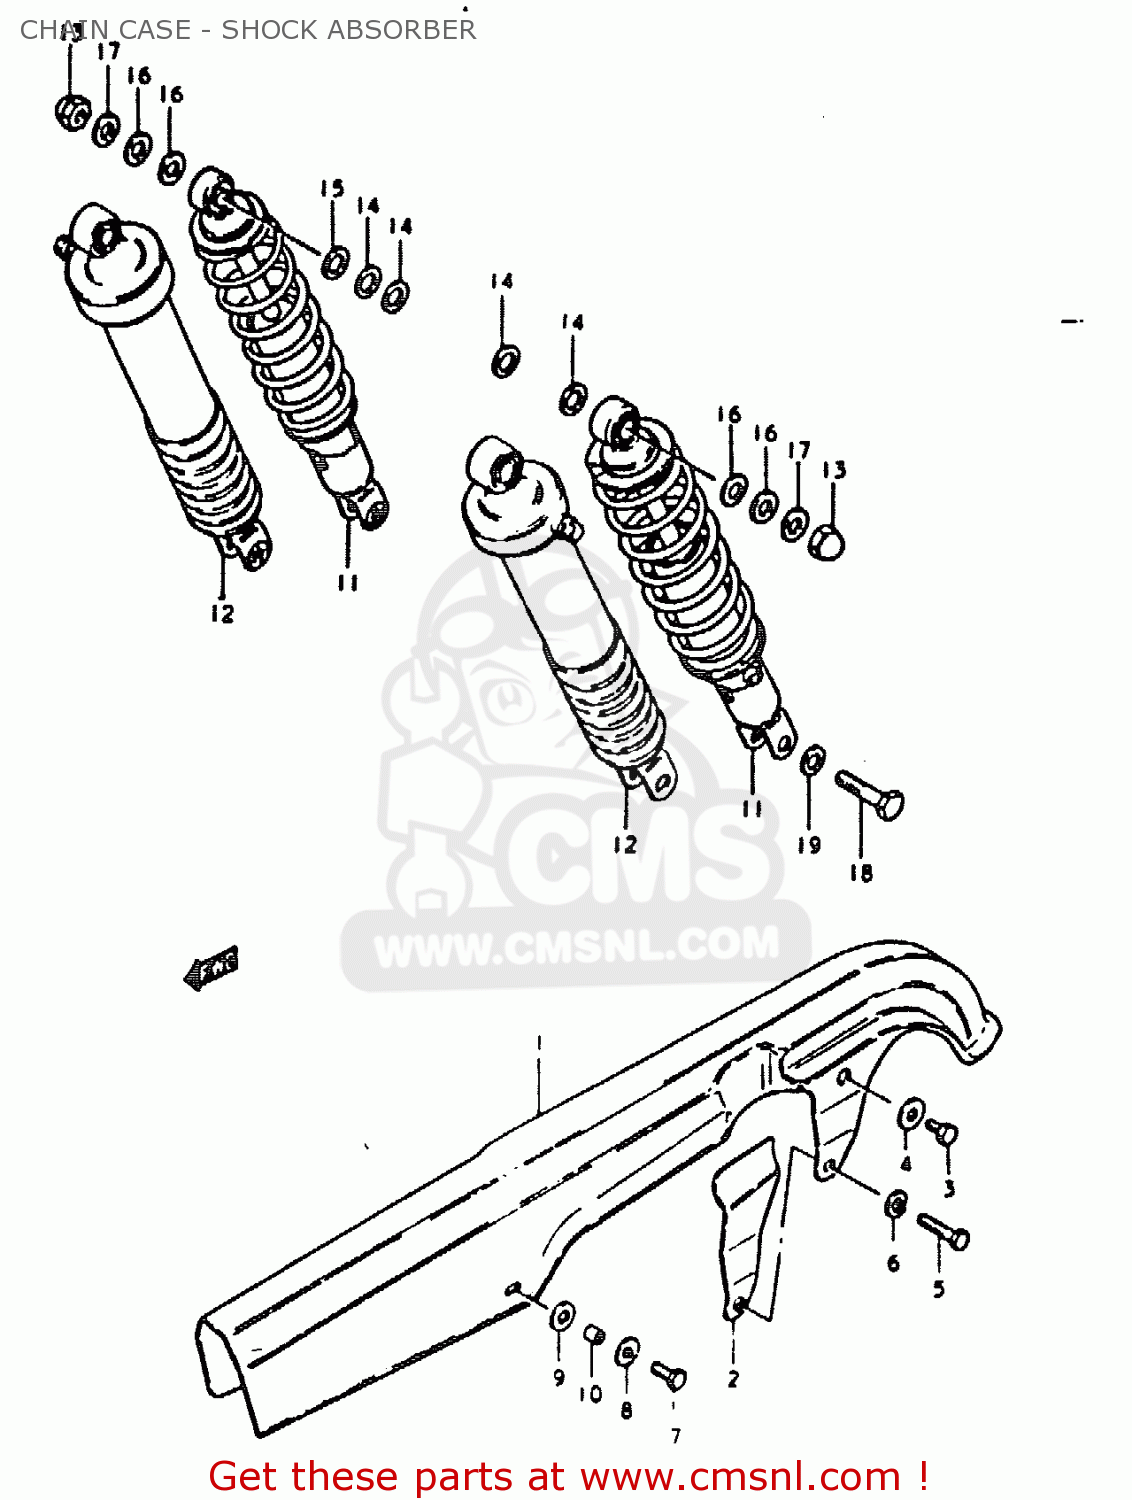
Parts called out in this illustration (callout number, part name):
1	CASE,CHAIN
2	REINFORCEMENT,CHAIN CASE
3	BOLT(6X8)
4	WASHER
5	BOLT
6	LOCK WASHER
7	BOLT
8	WASHER(6.5X18X1)
9	CUSHION
10	SPACER (6.1X8X5.2)
11	ABSORBER ASSEMBLY,REAR SHOCK
13	NUT, LOWER LH
14	WASHER
15	WASHER (12.5X24X3.2)
16	WASHER
17	WASHER(10.5X24X3.2)
18	BOLT(10X36)
19	WASHER
